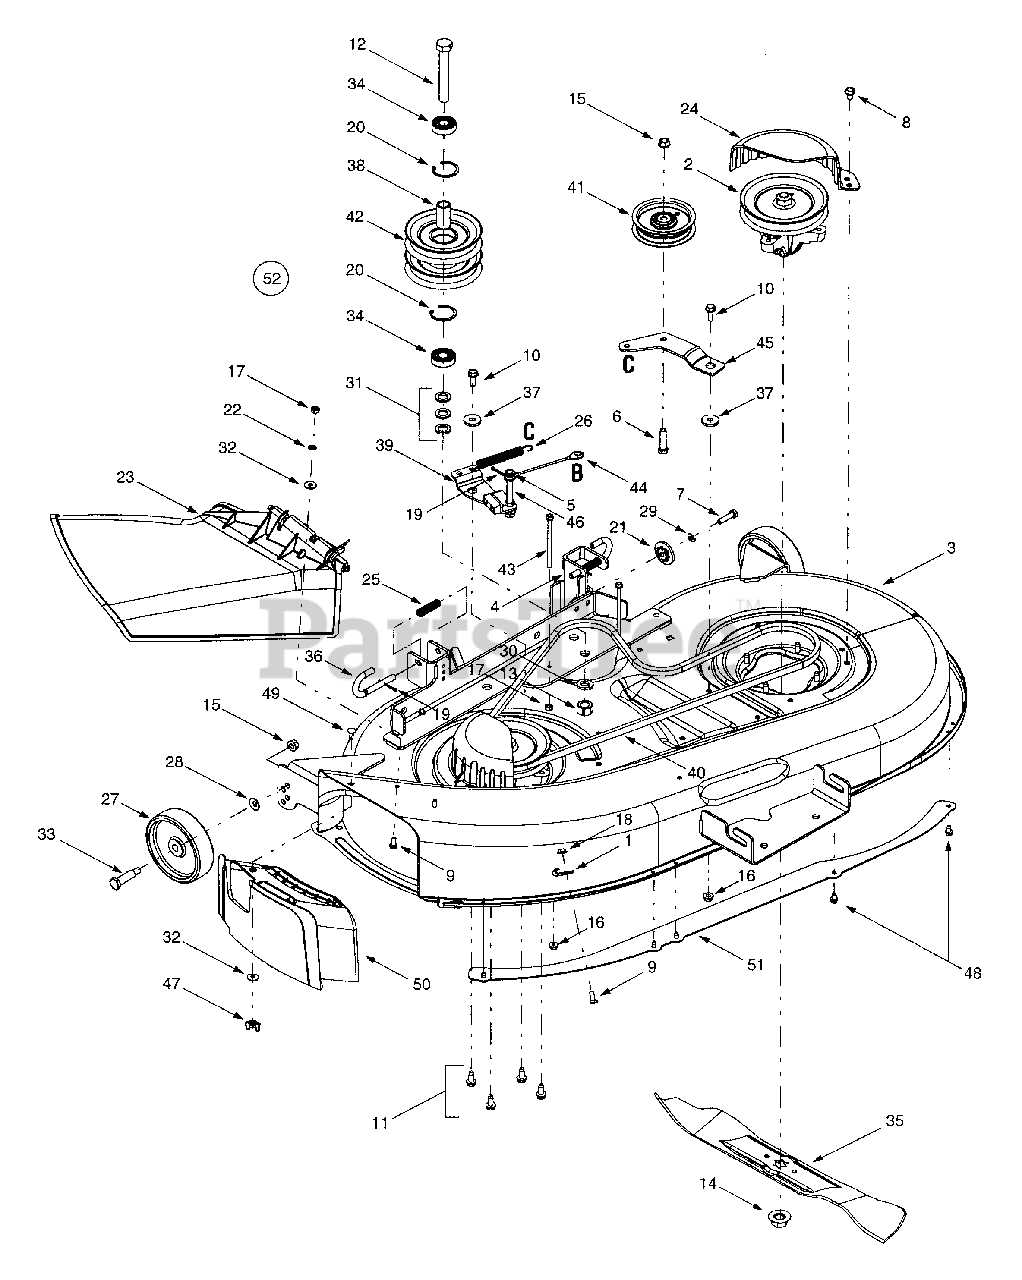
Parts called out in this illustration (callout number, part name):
1	Retainer Hook
2	Spindle Assembly, 5.75 Dia.
5	Flat Washer, .385 x .62 x .063
6	Hex Cap Screw, 1/4-20 x 1.5
7	Hex Cap Screw, 5/16-18 x 1.25
8	Self-tapping Screw, 5/16-18 x .625
9	Hex Cap Screw, 1/4-20 x .62
10	Hex Head Washer Screw, 5/16-18 x .875
11	Self-tapping Screw, 5/16-18 x .75
12	Hex Cap Screw, 5/8-18 x .875
13	Hex Nut, 5/8-18
14	Hex Flange Nut, 5/8-18
15	Flange Lock Nut, 3/8-16
16	Flange Lock Nut, 5/16-18
17	Hex Nut, 1/4-20
18	Hex Flange Lock Nut, 1/4-20
19	Cotter Pin, 1/8 x 1.25
20	Internal Snap Ring
21	Deck Adjustment Gear
22	Push Nut. .25 x .5
23	Side Discharge Chute Assembly
24	Belt Cover
25	Compression Spring, .406 x .531 x 1.75
26	Extension Spring, .50 x 4.74
27	Deck Wheel, 5 x 1.38
28	Bell Washer, .401 x .87 x .063
29	Lock Washer, 5/16
30	Lock Washer, 5/8
31	Flat Washer, .64 x 1.0 x .12
32	Bell Washer, .265 x .75 x .062
33	Shoulder Screw, .498 x 1.53
34	Bearing, .625 x 1.574 x .470
35	Three-in-one Blade, Star Center, 21.23"
36	Deck Release Pin
37	Shoulder Spacer, .625 x .324
38	Spacer, .635 x .88 x 1.72
39	Deck Brake Assembly
40	Deck Belt
41	Idler Pulley, 3.5
42	Double Pulley, 5.0
43	Self-tapping Screw, 1/4-20 x 4.0
44	Brake Cable, 5.05
46	Pin, 3/8-16, 3/8 x 3.27
47	Wing Nut, 1/4-20
48	Self-tapping Screw, 1/4-20 x .5
49	Carriage Screw, 1/4-20 x .62
50	Mulch Plug
